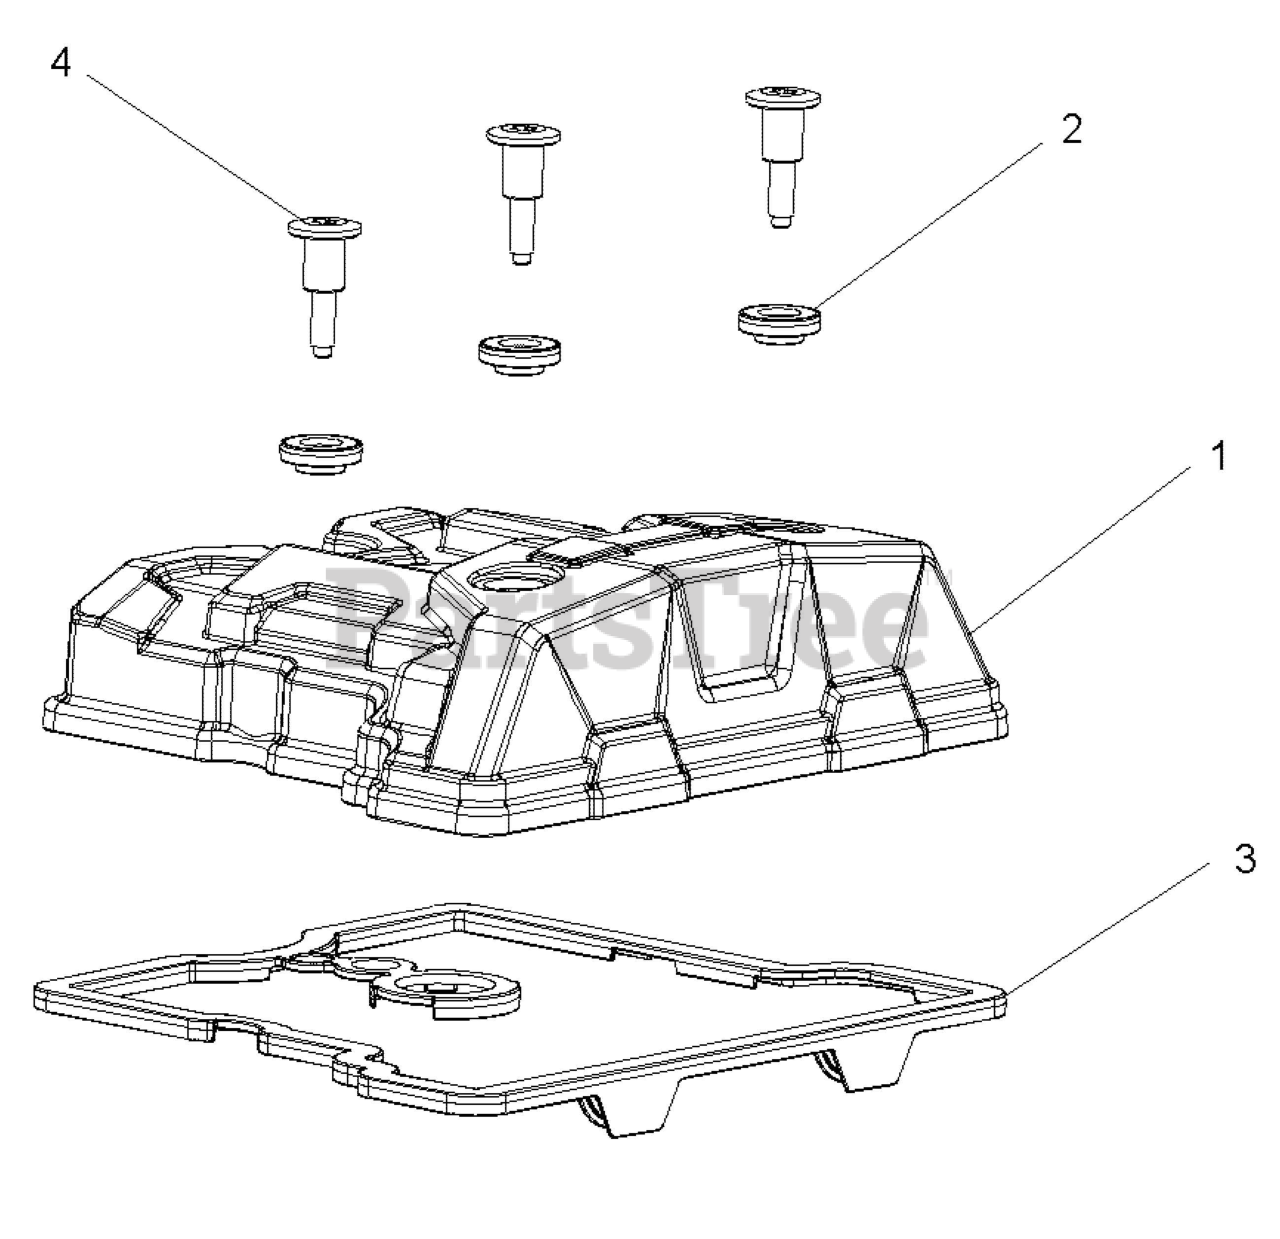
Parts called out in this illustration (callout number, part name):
1	COVER-VALVE,CAST,1CYL,DOHC
2	ISOLATOR-VALVE COVER
3	SEAL, VALVE COVER,1CYCL,DOHC
4	BOLT-SHLDR,M6X12X15
